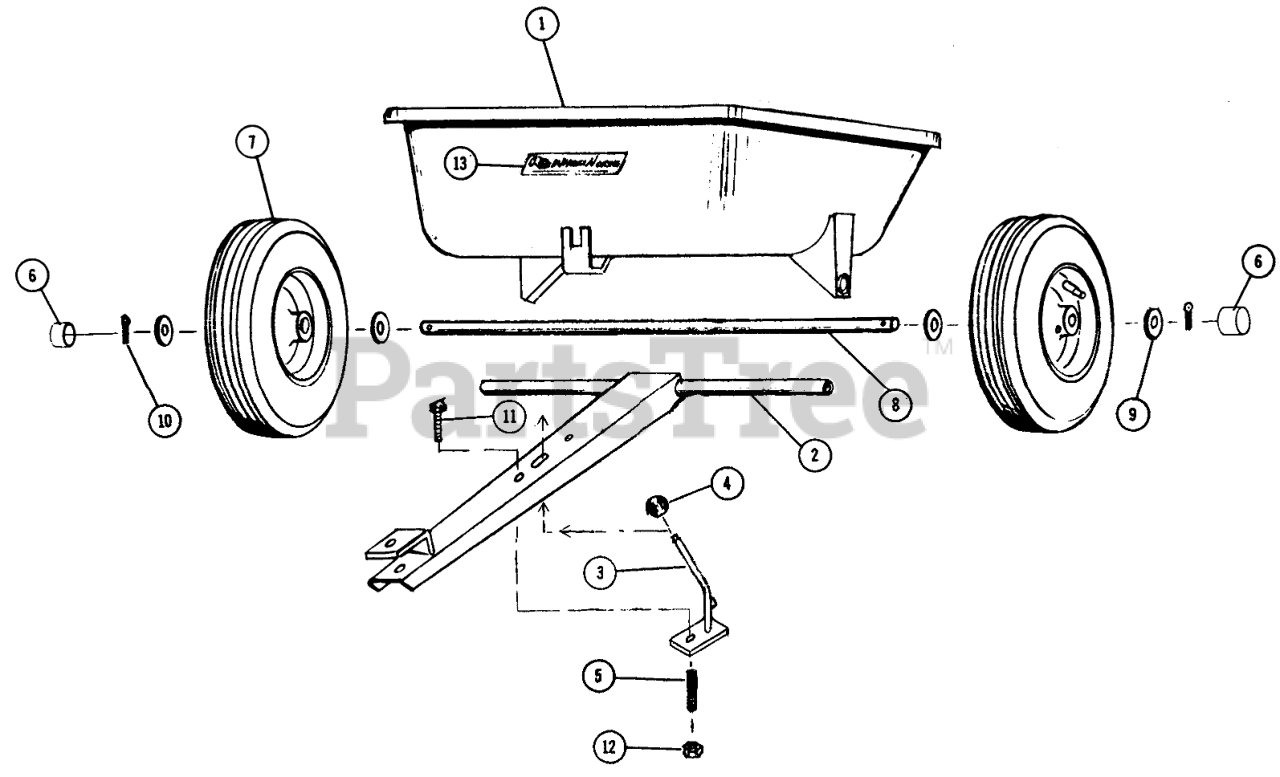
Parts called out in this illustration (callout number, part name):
1	Box Ass-y.
2	Frame Ass-y.
3	Latch Ass-y. W/A
4	Knob
5	Spring
6	Hub Cap
7	Tire & Wheel
8	Axle
9	WASHER
10	Cotter Pin 3/16 x 1
11	Bolt Hex 5/6-18 X 2-1/2
12	Nut-Nylok
13	Decal
